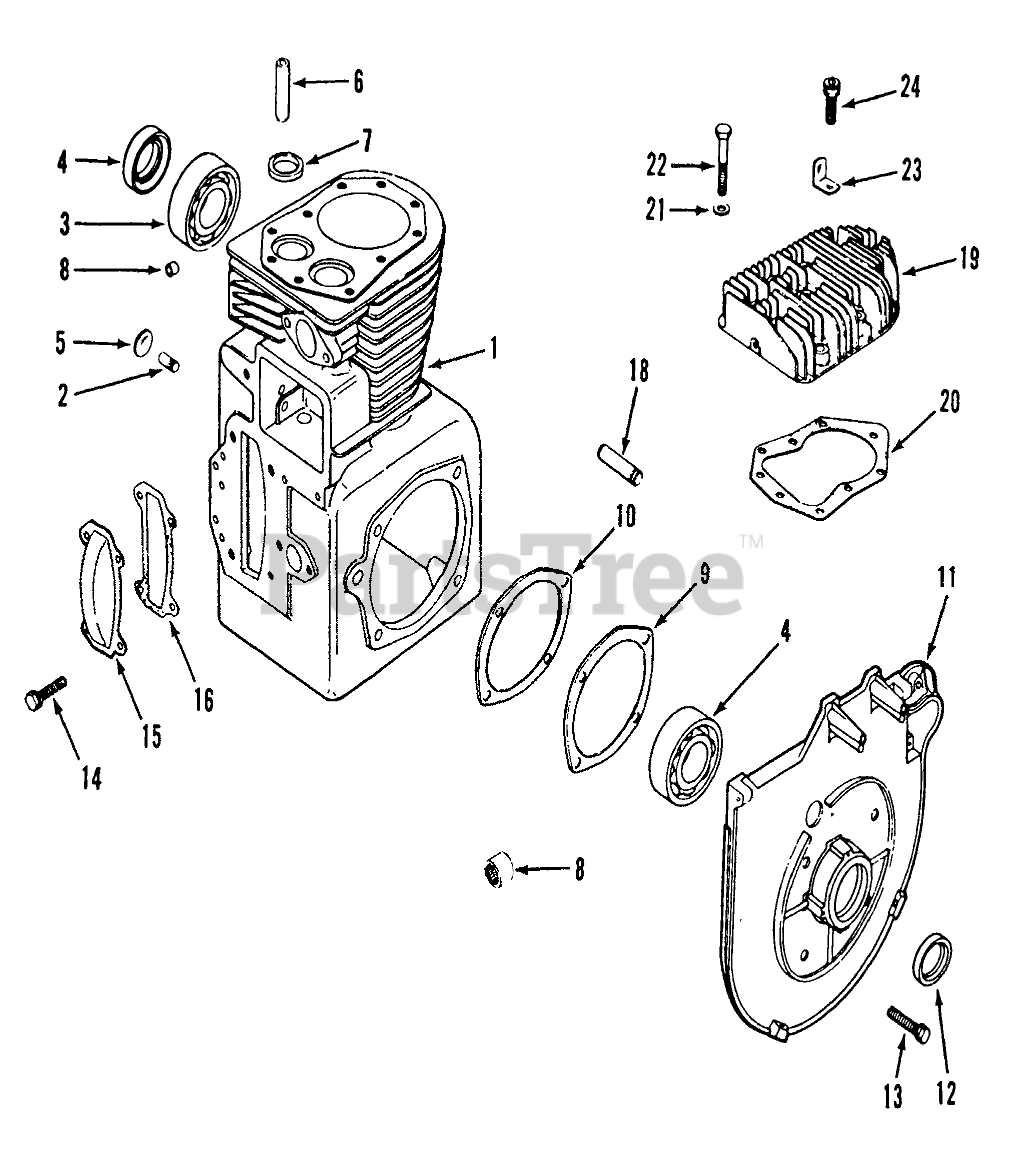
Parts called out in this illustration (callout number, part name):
1	Cylinder Block-Service With Short Block (Includes Crankshaft) 312
2	Shaft-Govemor
3	Ball Bearing
4	Seal-Rear Oil
5	Plug
6	Guide-Valve
7	Insert
8	Bearing
9	Gasket-Bearing Plate
10	Gasket-Shim
11	Bearing Plate
12	Seal-Front Oil
13	Screw
14	Screw
15	Camshaft Cover
16	Gasket
18	Shaft
19	Head-Cylinder
20	Head Gasket
21	Washer
22	Screw
23	Strap-Lifting
24	Screw-Hex Soc Hd
